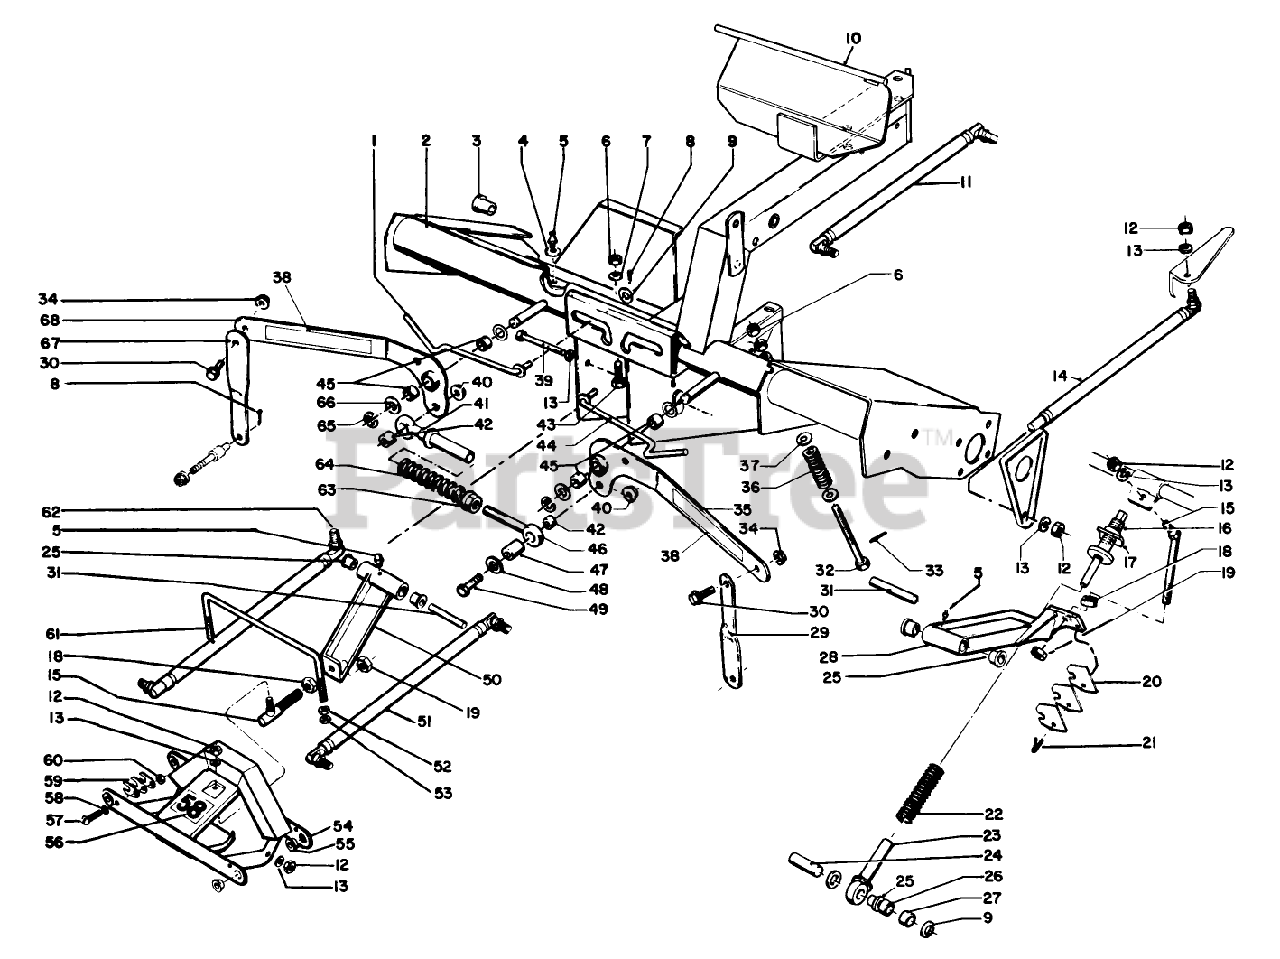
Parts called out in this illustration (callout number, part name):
3	3/4IDX1LG FLANGE BSHG
4	WASHER-LOCK
5	FITTING-GREASE
6	NUT-HEX
7	WASHER-LOCK
8	PIN-COTTER
9	WASHER-FLAT
12	NUT-HEX
13	WASHER-LOCK
15	BALL JOINT
16	ANCHOR, SPRING COBAL
17	ADJUSTING NUT
18	NUT-JAM
19	NUT-LOCK, NI
21	PIN-COTTER
22	COMPRESSION SPRING
23	GUIDE BUSHING WA
25	BUSHING-FLANGE
26	SPLIT SPACER
30	SHOULDER BOLT
33	PIN-ROLL, SLOTTED
34	NUT-LOCK
36	SPRING
37	WASHER-PLAIN
38	DECAL-WARNING
39	SCREW-HH
42	BUSHING
43	SCREW-HH
45	BUSHING
48	WASHER-FLAT
49	SCREW-HH
52	NUT-HEX
54	Intermediate Frame (Incl. Ref. #55)
55	BUSHING-FLANGE
57	10-24 X 7/8 RND HD MS
58	SPACER
59	FRONT SIDE SHIM
60	NUT-LOCK, NI
63	NUT-LOCK, FLANGE
65	RING-RETAINING, EXTERNAL
66	WASHER-FLAT
